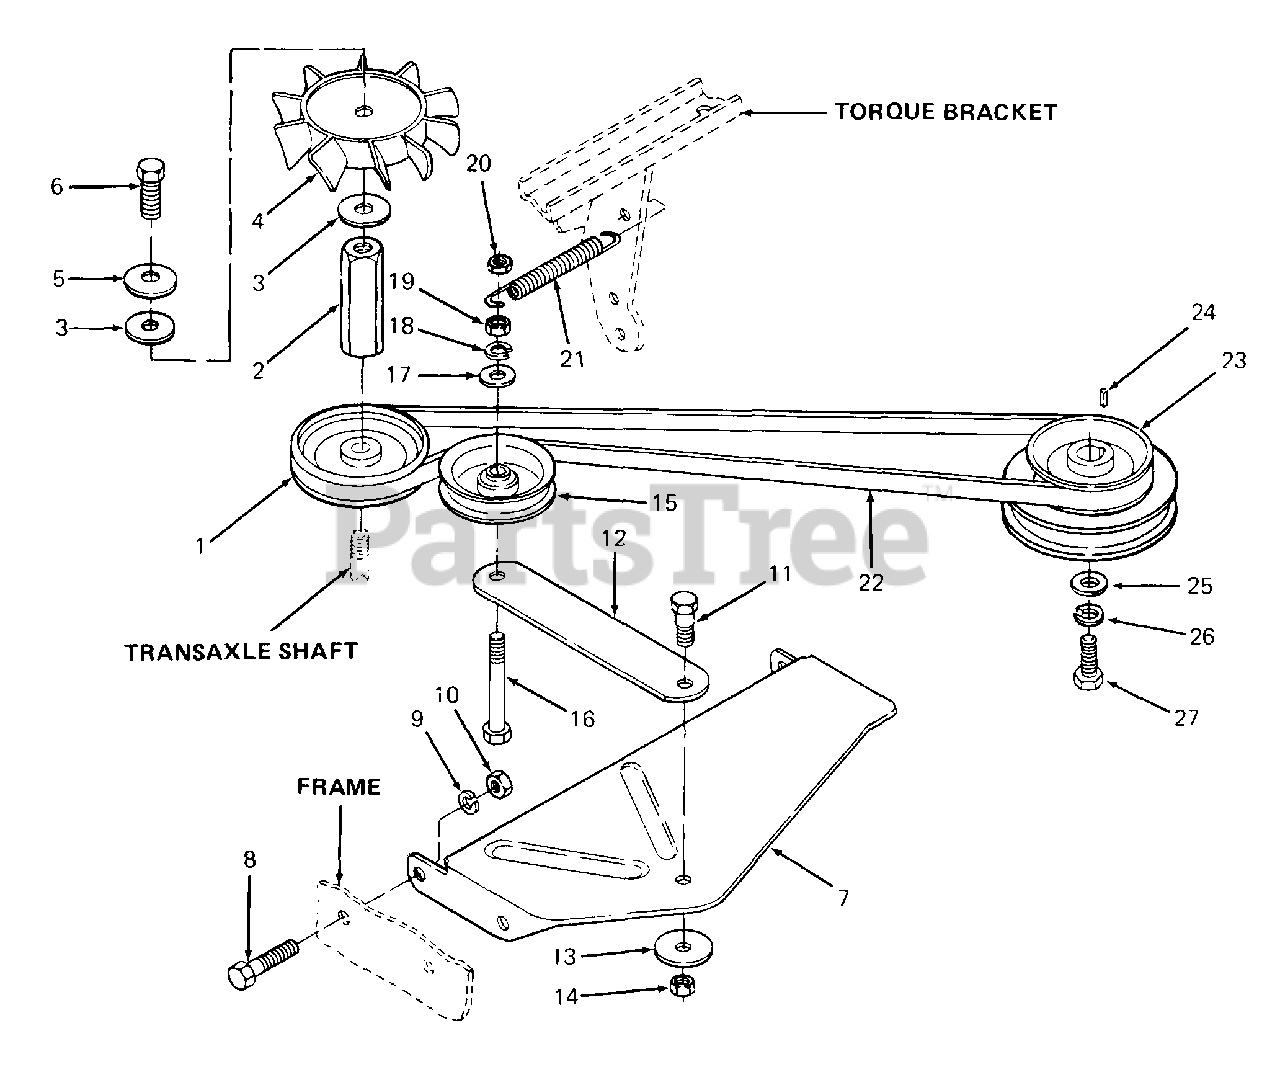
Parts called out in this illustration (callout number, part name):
1	V-Pulley, 4.0 Dia
2	Adapter, Fan, 2.0 Lg
3	Washer, Flat, .531 X 1.5 X .120 Thk
4	Fan, 10 Blade Hydro
5	Washer, Bell, .505 X 1.00 X .075
6	Bolt, Hex, 1/2-20 X .75 Lg GR5
7	Bracket, Clutch Mounting
8	Screw, Hex Cap, 5/16-18 X .62 Lg
9	Washer, Lock, 5/16
10	Nut, Hex, 5/16-18 GR5
11	Screw, Shoulder
14	Nut, Hex Center Lock, 5/16-18 GR5
15	Idler, Flat, 2.75 Dia
16	Screw, Hex Cap, 3/8-16 X 2.25 Lg GR5
17	Washer, Flat, .406 X .75 X .063 Thk
18	Washer, Lock, 3/8
19	Nut, Hex, 3/8-16 GR5
20	Nut, Hex Center Lock Jam, 3/8-16
21	Spring, Extension
22	V-Belt, A Sec X 80 in. Lg
23	Pulley, Engine, 3.5 Dia
24	Key, Square, 1/4 X .75 Lg
25	Washer, Flat, .450 X 1.25 X .172 Thk HDN
26	Washer, Lock, 7/16
27	Screw, Hex Cap, 7/16-20 X 1.5 Lg
